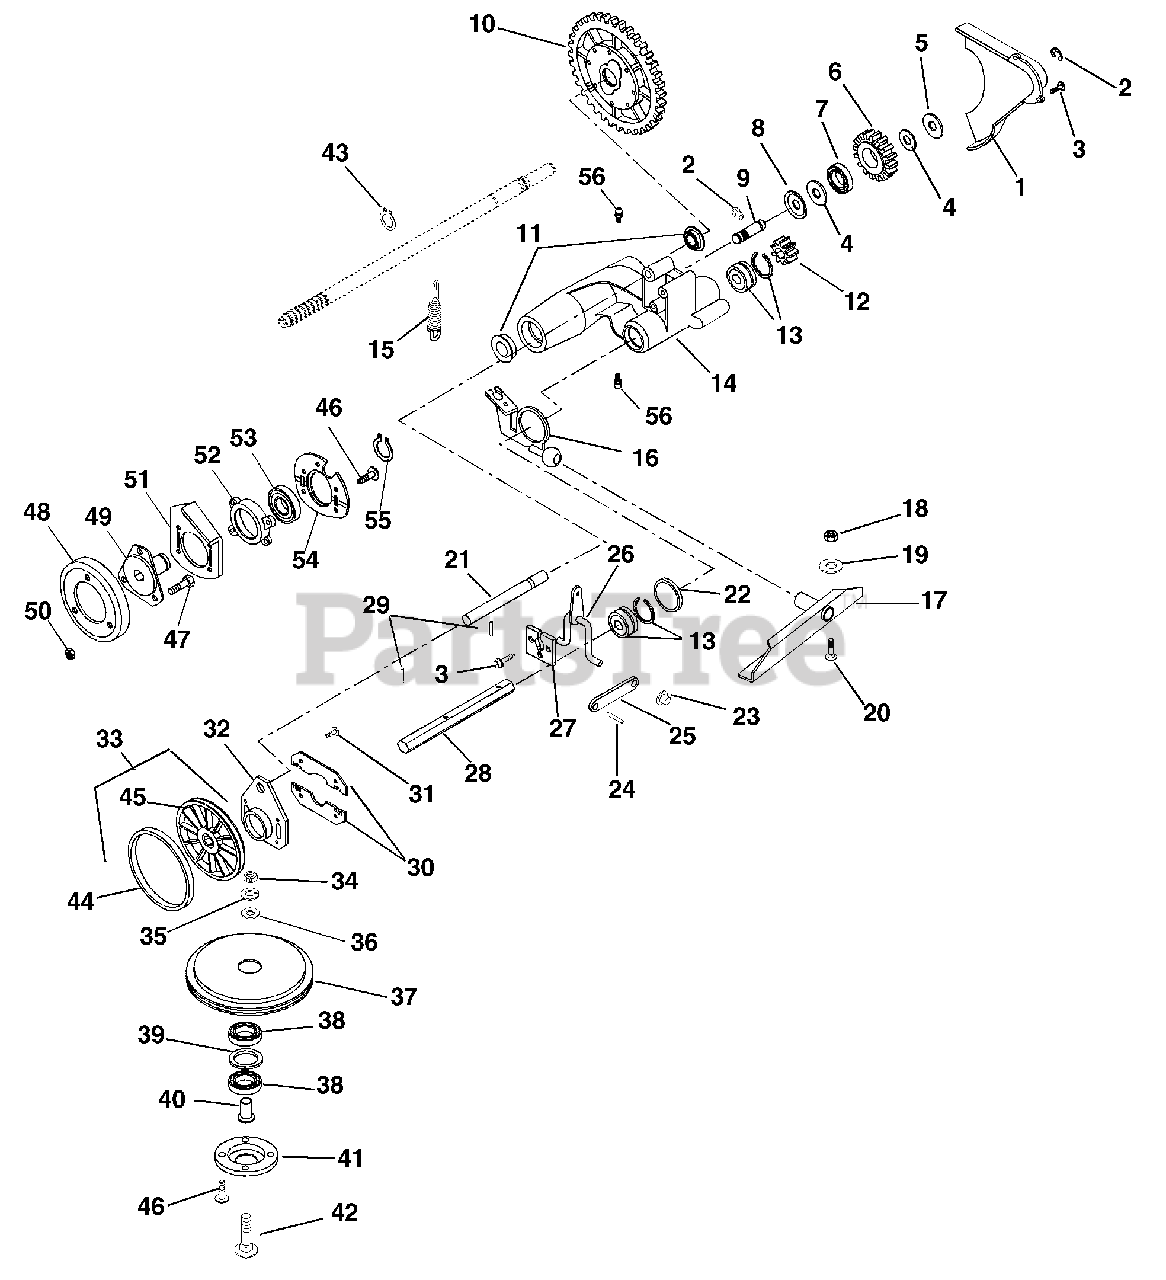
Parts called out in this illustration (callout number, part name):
1	COVER, GEAR
2	RG-RTNG-EXT .438X.035
3	@SCR-TAP 12-24X.50 HWH TR YWZC
4	WSHR-FL-STL .52X.827X.062 YWZC
5	WSHR-FL-STL.531X1.00X.063 YWZC
6	IDLER GEAR
7	BRG-BALL .500X1.38X.437
8	RETAINER
9	IDLER SHAFT
10	DIFFERENTIAL ASSEMBLY
11	BRG-BALL .625X1.383X.50
13	BRG-BALL .562X1.375X.437
14	DRIVE MOUNT
15	SG-TENS .051X.60X2.25 WLD 7.0
16	DRIVE ACTUATOR WELDMENT
17	PIVOT, CHANNEL WELDMENT
18	@NUT-LK-CTR .31-18 YWZC
19	@WSHR-FL-STL.344X.688X.065YWZC
20	@BLT-RHDSSQNK .31-18X.62 G5YZ
21	ROD - GUIDE
22	WSHR-FL-STL 1.390X2.00X.020 PL
23	PUSH NUT, .25
24	PIN-ROLL .125X.50
24	PIN-ROLL .125X.63
25	SHIFT LINK
26	SHIFT ARM WELDMENT
27	RETAINER PLATE
28	HEX SHAFT
29	PIN-ROLL .188X.88
30	THRUST PLATE
31	@SCR-TAP 10-24X.375 HWH YZ TR
32	GUIDE PLATE
33	FRICTION WHEEL ASSEMBLY
34	@NUT-HEX .31-18 YWZC
35	WSHR-LK .312X.097 HVY YWZC
36	WSHR-FL-STL .328X.875X.062YWZC
37	FRICTION SHEAVE
38	BRG-BALL .625X1.375X.43
39	WSHR-FL-STL 1.062X1.344X.032PL
40	SPINDLE - BEARING
41	RETAINER - BEARING
42	@BLT-RDHDSQNK .31-18X1.75 G5YZ
43	RG-RTNG-EXT .579X.035
44	RING, FRICTION
45	FRICTION WHEEL HUB
46	@SCR-TAP 12-24X.50 HWH TR YWZC
47	@BLT-HEX .25-20X.50 GR5 YWZC
48	DISC, FRICTION - 716 MAT'L
49	FRICTION WHEEL HUB
50	@NUT-LK-CTR .25-20 YWZC
51	BEARING PLATE
52	BEARING RETAINER
53	BRG-BALL 1.0X2.0X.56 (1641)
54	BEARING RETAINER
55	RG-RTNG-EXT 1.00X.042
56	FTG-LUBE .25-28X.256 YWZC
56	LM BEARING SERVICE KIT
